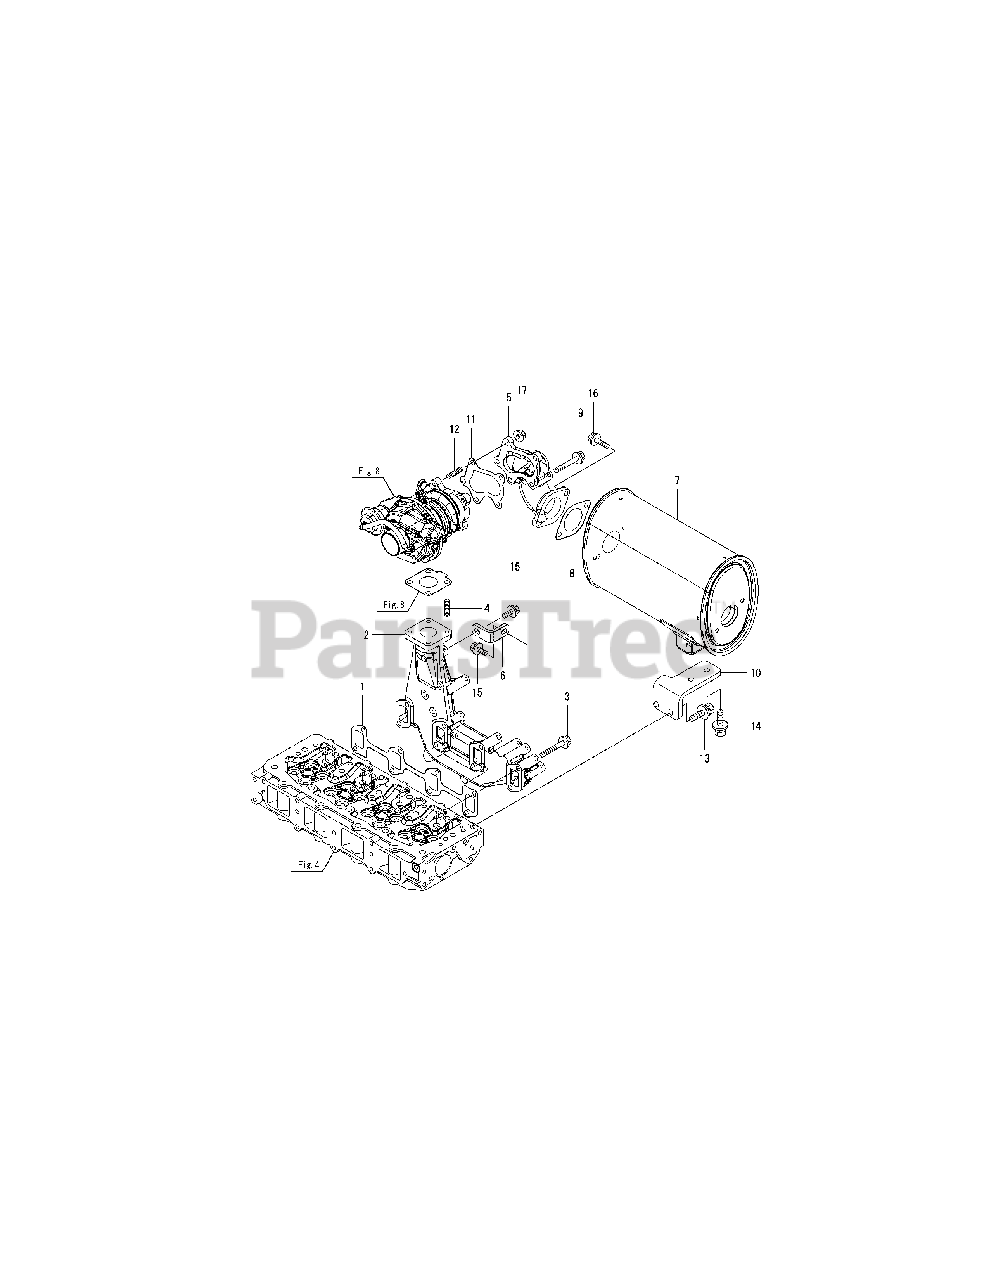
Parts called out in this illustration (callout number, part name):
1	GASKET, EXH.MANIFOLD
2	MANIFOLD, EXHAUST
6	STIFFENER,EXH. BEND
8	GASKET, NOZZLE
10	STAY, SILENCER
11	GASKET, TURBINE OUT
15	BOLT M 8X 16 PLATED
16	BOLT M 8X 30 PLATED
